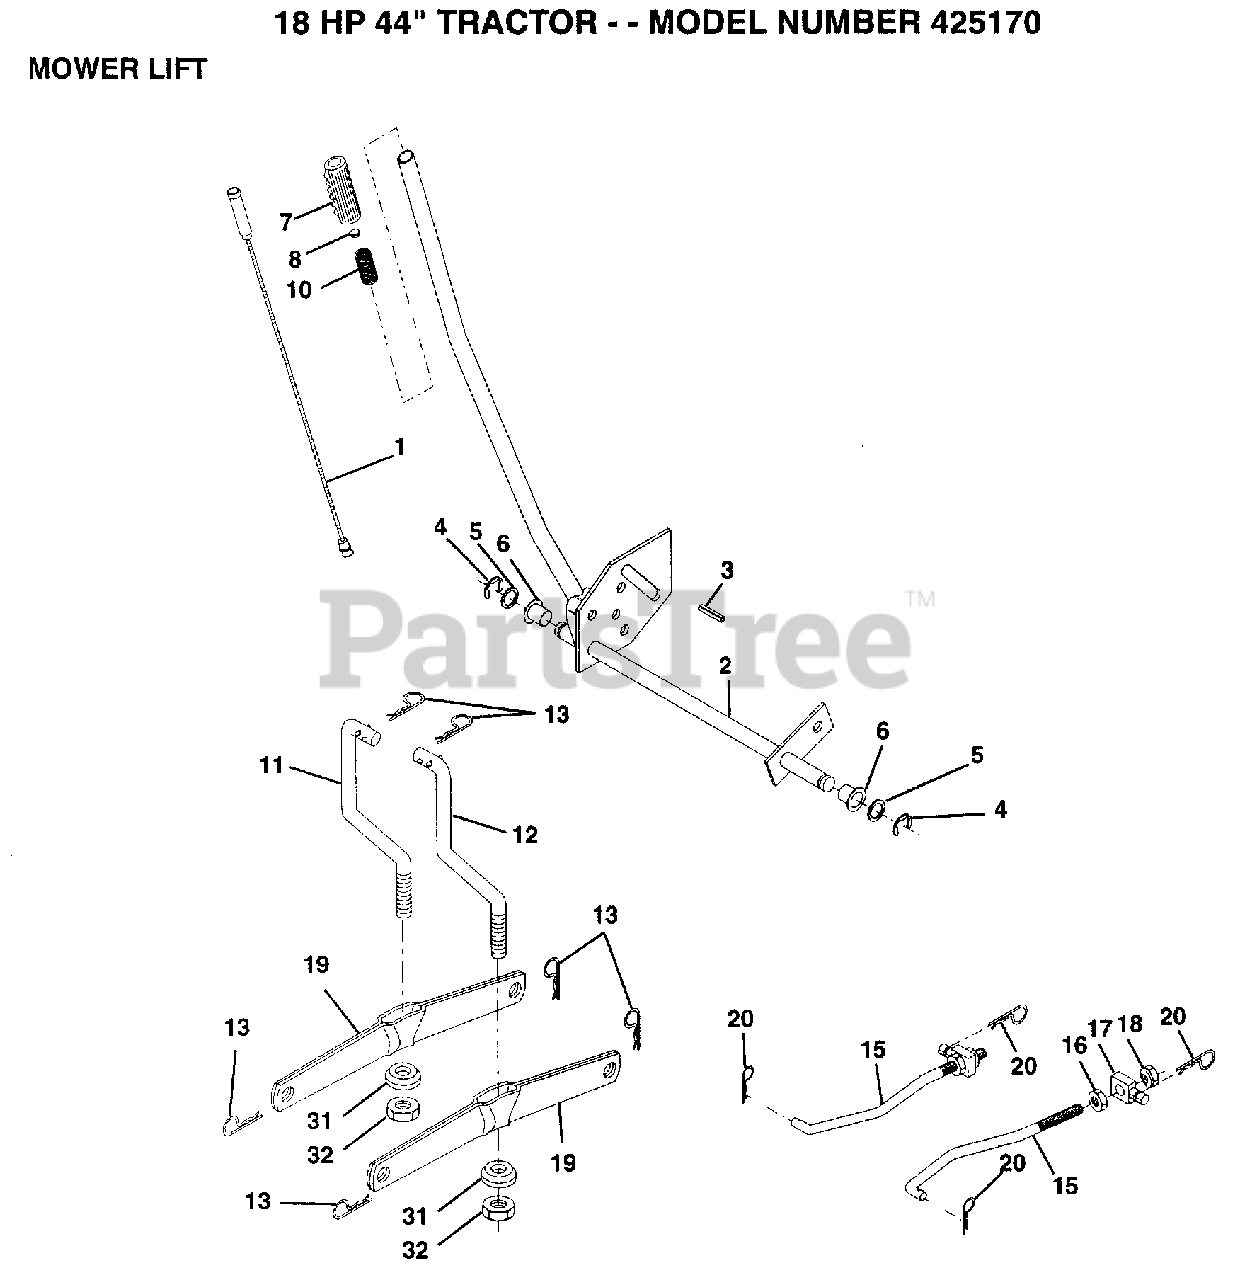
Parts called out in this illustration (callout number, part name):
1	WIRE ASM
2	SHAFT.ASM.LIFT LH
3	PIN GROOVE
5	WASHER
6	NYLON BEARING
7	GRIP
15	LINK.FRONT
16	NUT
17	TRUNION
18	NUT.LK.W/WSH.1/2.
19	ARM SUSP REAR
20	RETAINER.SPRING
31	BEARING PVT LH
32	NUT.LOCK.3/8-24
